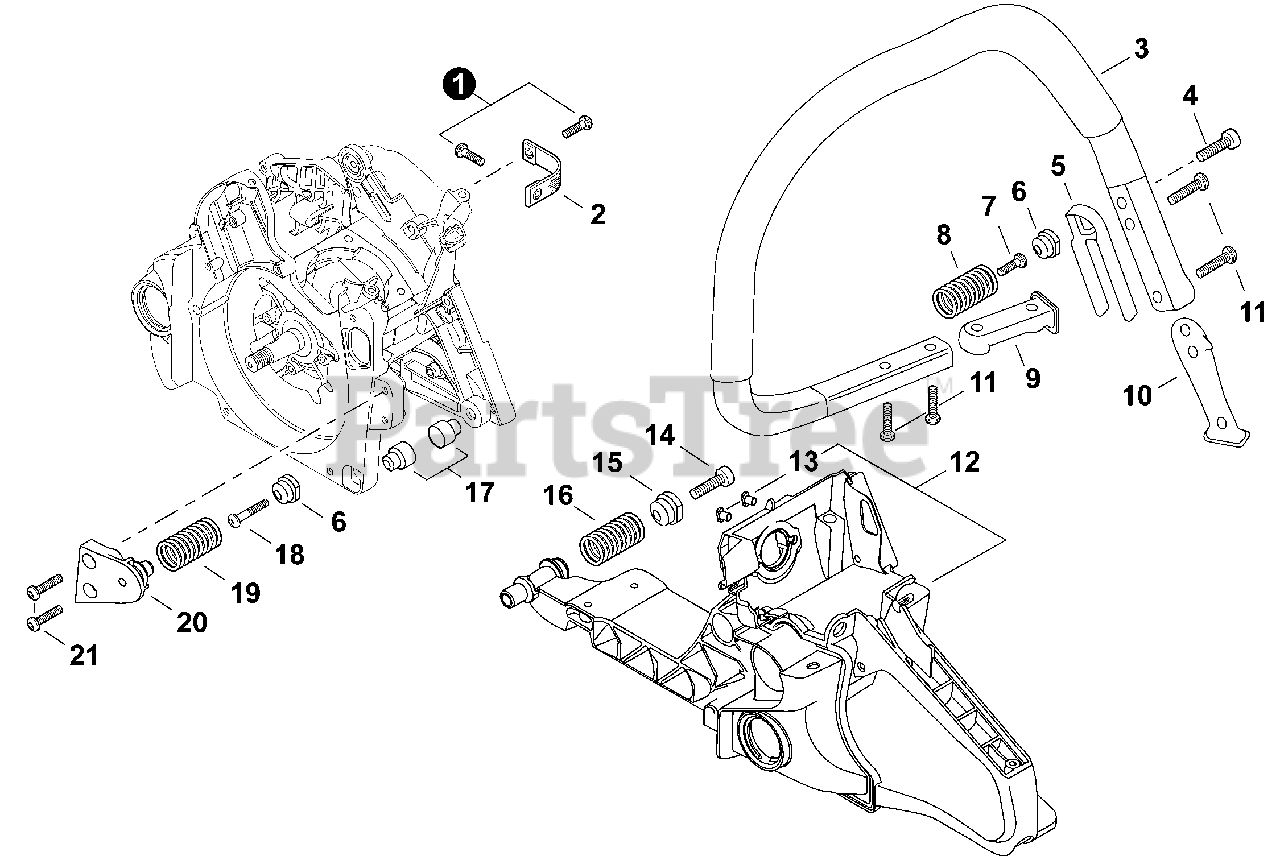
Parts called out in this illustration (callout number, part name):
1	BOLT, TORX 5×16
2	STRAP, SAFETY
3	HANDLE, FRONT
4	BOLT, TORX 6×20
5	HOLDER, SPRING
6	HOLDER, SPRING 14.4
7	BOLT, TORX 5×16
8	SPRING, COMPRESSION 17×38.4×2.6
9	MOUNT, HANDLE
10	MOUNT, HANDLE
11	BOLT, TORX 5×20
12	HANDLE, REAR
14	BOLT, TORX 6×20
15	HOLDER, SPRING 17
16	SPRING, COMPRESSION 20×40×3.3
17	CUSHION
18	BOLT, TORX 5×25
19	SPRING, COMPRESSION 17×36.7×2.6
20	HOLDER, SPRING
21	BOLT, TORX 5×20
